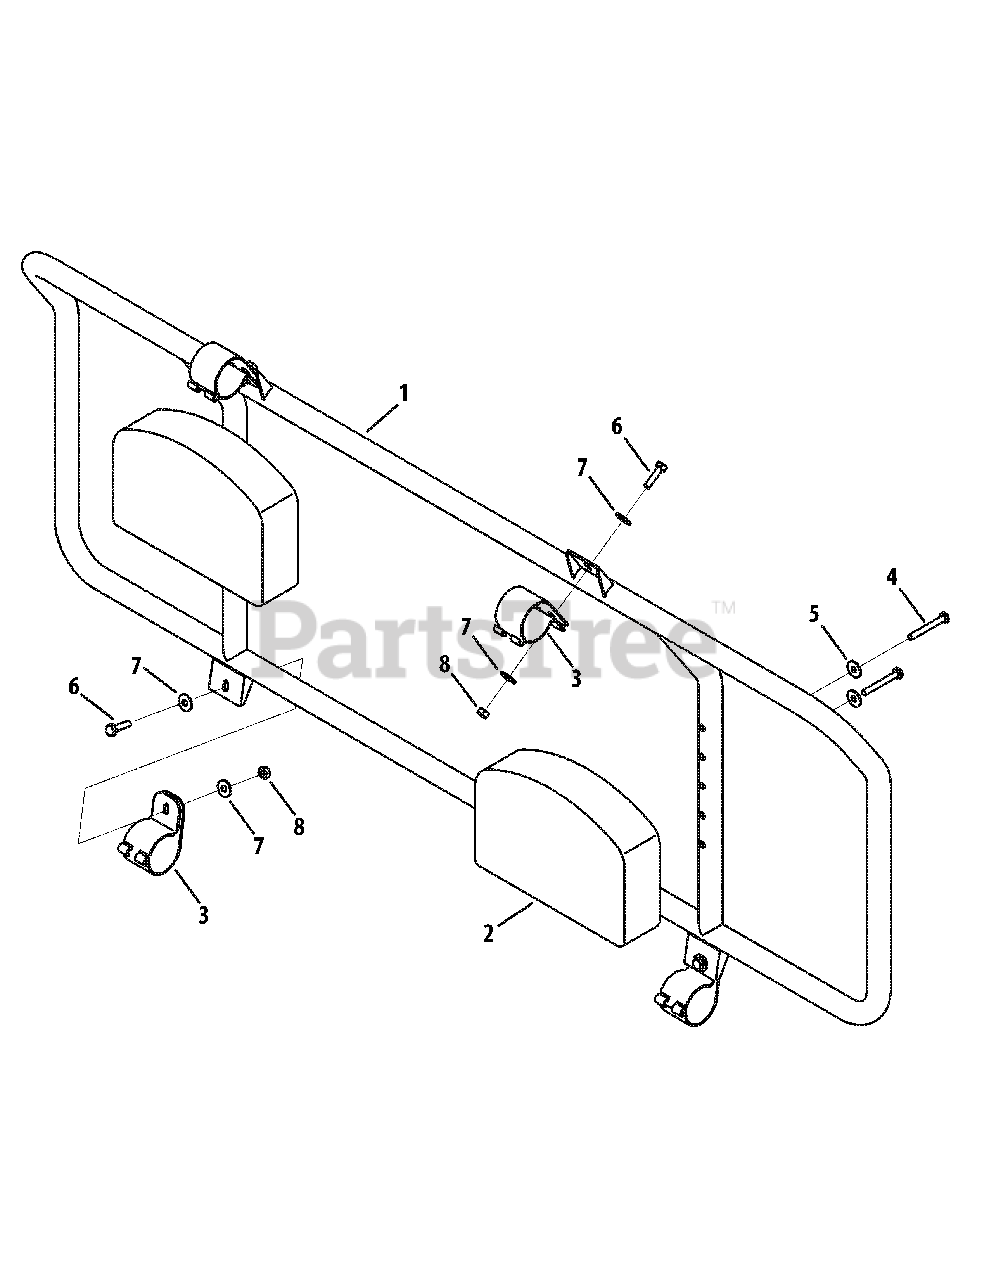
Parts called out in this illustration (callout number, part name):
1	Main Frame Tube
4	Hhcs, M8-1.25 x 45.00 Lg
5	Wash, Flat, .330 x .630 x .0635
6	Hhcs, 1/4-20 x 1.00
7	Wash, Flat, .271 x .630 x .065
8	Nut, Hexlk, 1/4-20
